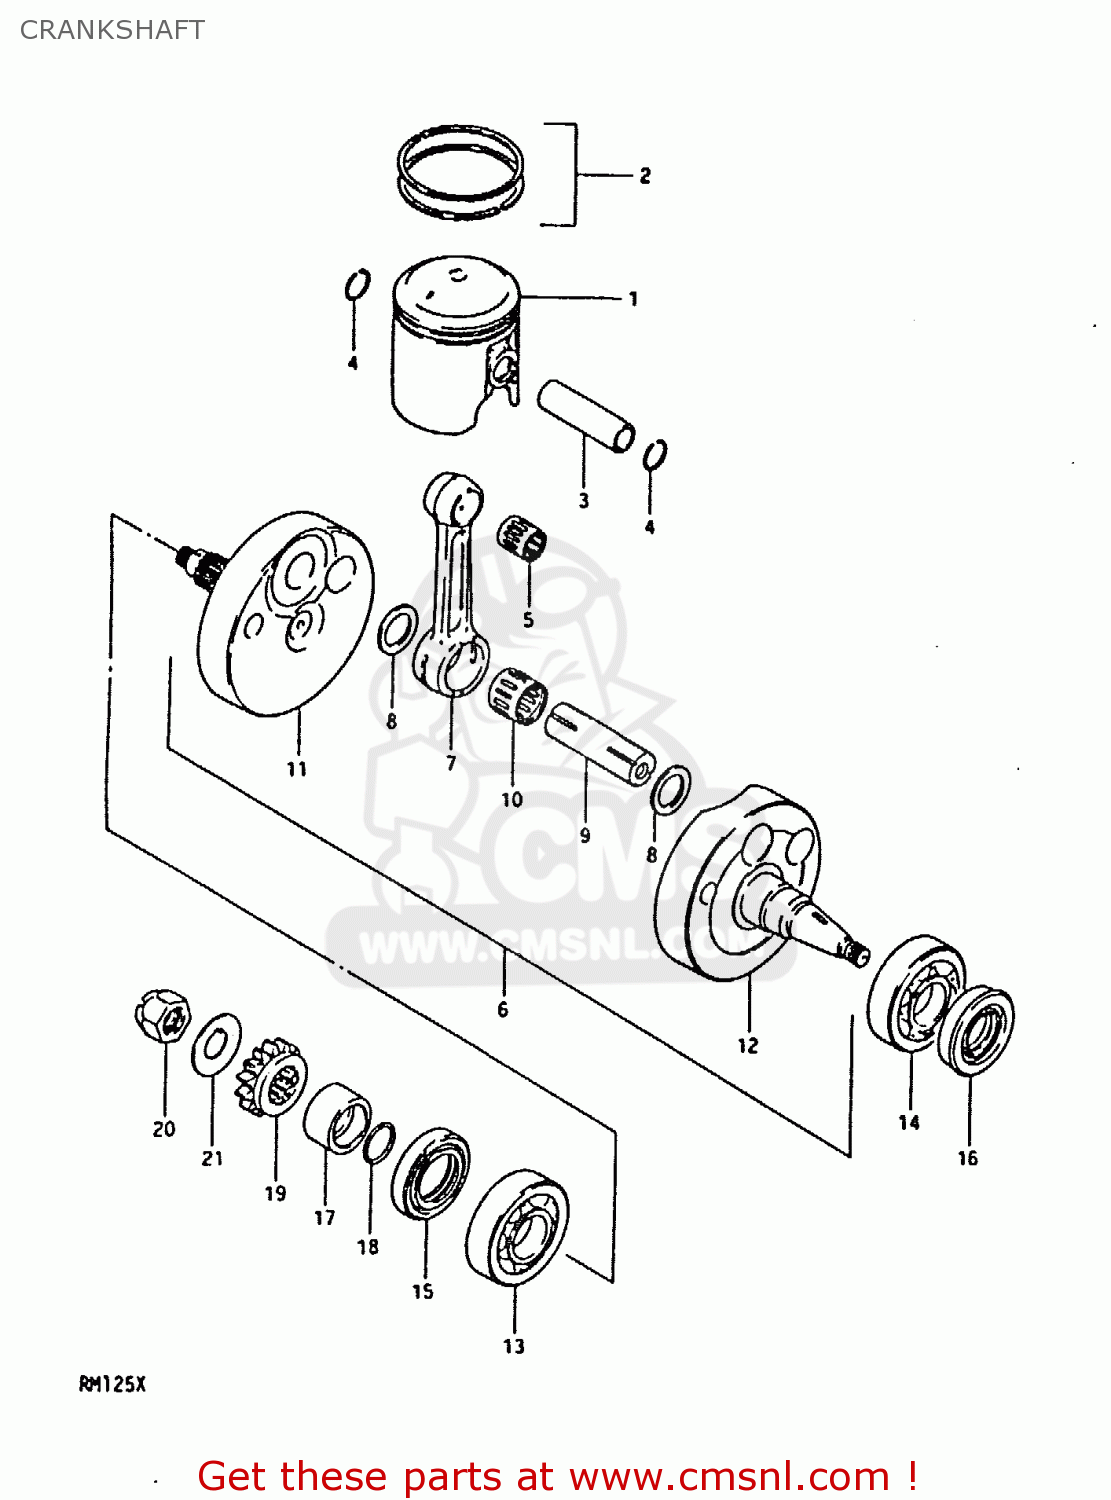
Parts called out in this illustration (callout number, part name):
1	PISTON
2	RING SET,PISTON
3	PIN,PISTON
4	RING,SNAP 14MM
5	BEARING
6	CRANKSHAFT ASSEMBLY
7	CONNECTING ROD
8	WASHER(19X32X1)
9	PIN,CRANK
10	BEARING(19X25X16)
11	CRANKSHAFT,RIGHT
12	CRANKSHAFT,LEFT
13	BEARING
14	BEARING
15	SEAL,OIL(28X40X8)
16	SEAL,OIL(19.6X37X8)
17	SPACER,PRIMARY DRIVE GEAR
18	O RING(D:2.4,ID:19.8)
19	GEAR,PRIMARY DRIVE
20	NUT
21	WASHER
